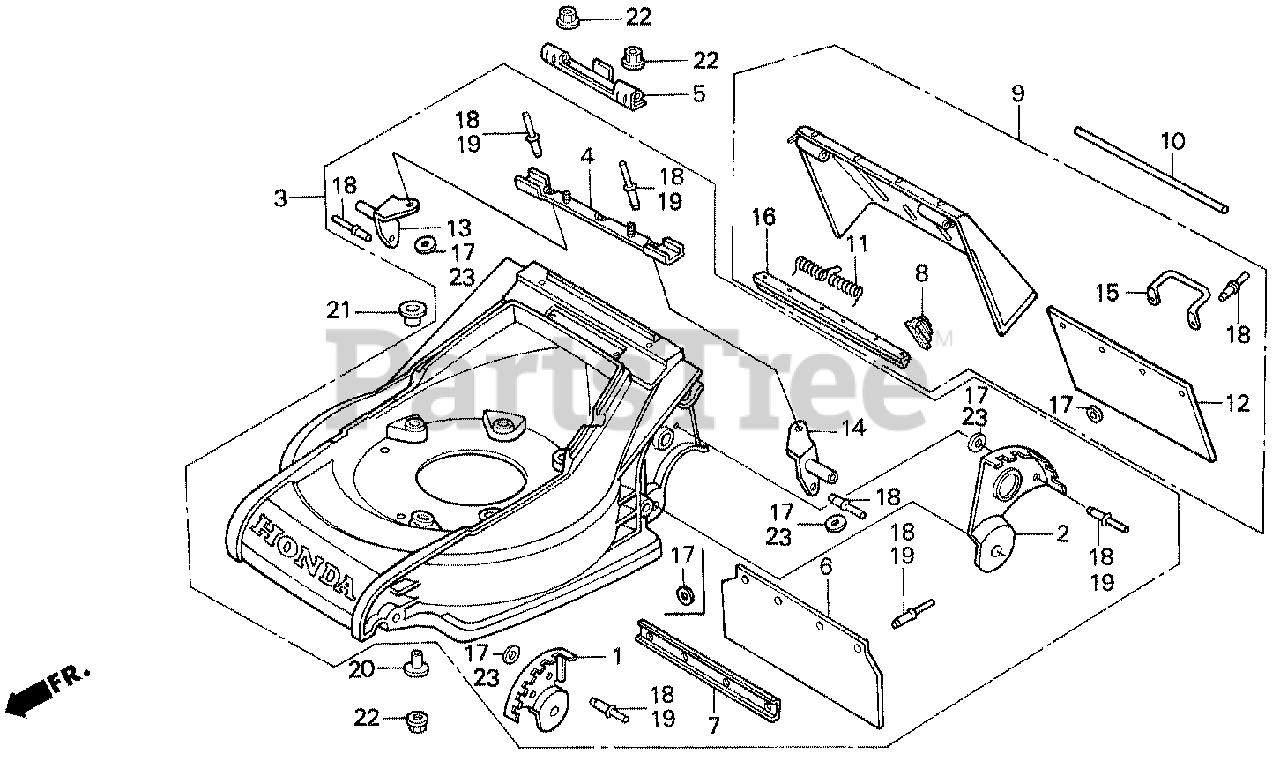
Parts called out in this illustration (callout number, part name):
1	PANEL, FR. ADJUSTING
2	PANEL, RR. ADJUSTING
3	HOUSING, CUTTER *NH246* (LOOSY GRAY)
4	HINGE, DISCHARGE GUARD
5	HINGE, DISCHARGE GUARD
6	SHIELD, SAFETY
7	PLATE, SAFETY SHIELD
8	STOPPER, DISCHARGE GUARD
9	GUARD, DISCHARGE
9	GUARD, DISCHARGE (NOT AVAILABLE)
10	SHAFT, DISCHARGE GUARD
11	SPRING, GUARD RETURN
12	SHIELD, DISCHARGE GUARD
13	STAY, R. HANDLE
14	STAY, L. HANDLE
15	GRIP, DISCHARGE GUARD
16	SEAL, DISCHARGE GUARD
17	WASHER, STOPPER
18	RIVET, BLIND (4.8MM)
19	RIVET, BLIND (4.8X18.2)
20	COLLAR, ENGINE BED
22	NUT, FLANGE (6MM)
23	WASHER, PLAIN (5MM)
